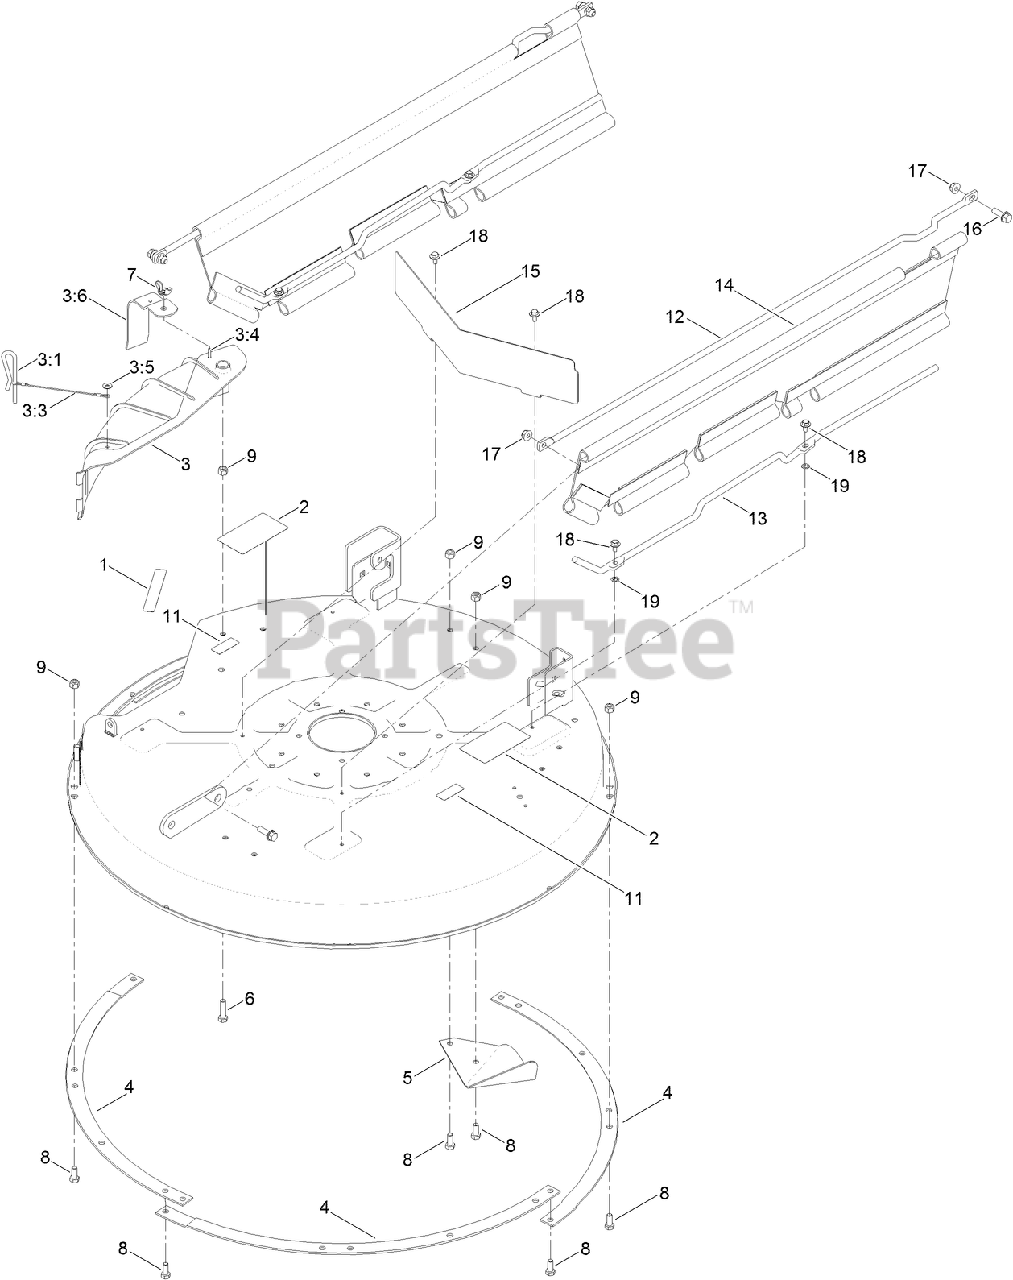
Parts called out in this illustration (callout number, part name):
1	DECAL-DANGER
2	DECAL-DANGER
3	DISCHARGE COVER ASM
3:1	PIN-LOCKING, CHUTE
3:3	LANYARD
3:4	RIVET-BLIND
3:5	WASHER-PLAIN
4	RING-DECK
6	SCREW-HH
7	NUT-WING
8	SCREW-HH
9	NUT-LOCK, NI
11	DECAL-DANGER
12	ROD-SUPPORT, UPPER
13	ROD-SUPPORT, LOWER
14	GUARD-SIDE
15	SHIELD-FRONT
16	SCREW-HSBH
17	NUT-HF, NI
18	SCREW-HHFTF
19	NUT-RETAINING
